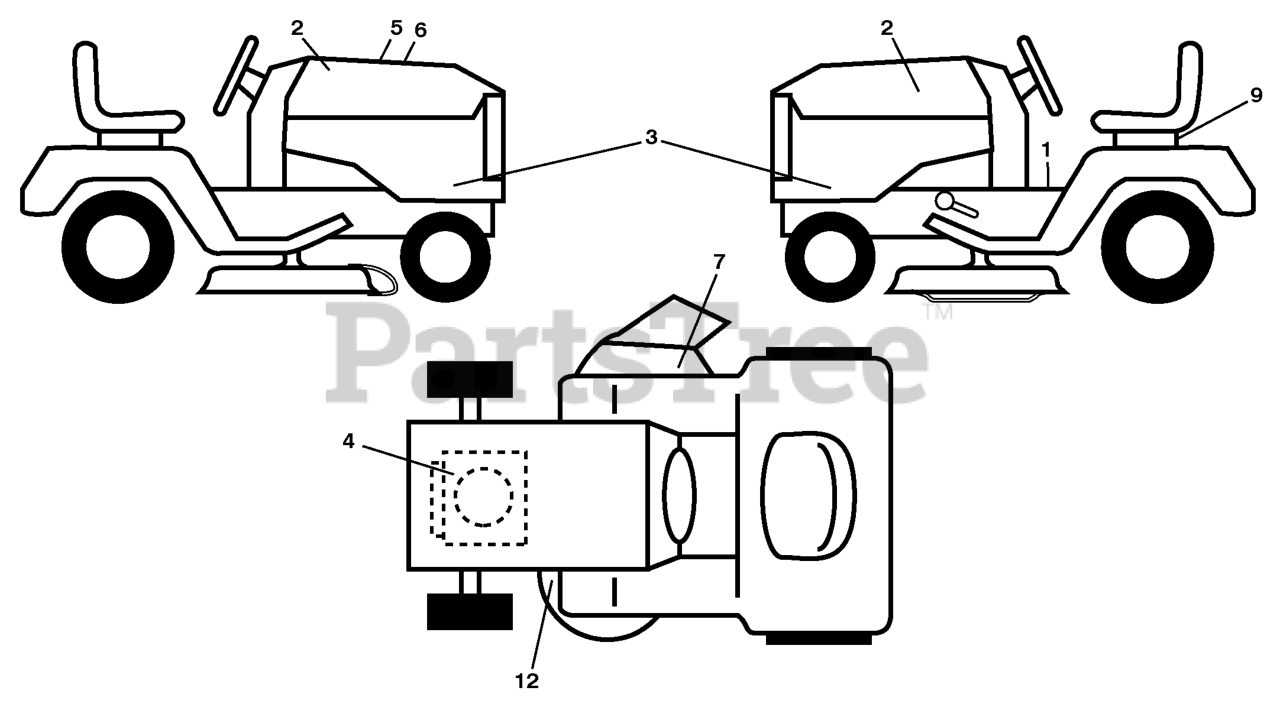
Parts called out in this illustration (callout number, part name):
1	DECAL.FENDER.WARNING.ENG
2	RP.DECAL.BADGE.170MM.TEXTLOGO
3	DECAL.SDPNL.YTH22V46.BS.HUSQ
4	Decal, Engine H.P.
5	DECAL.WARNING.CUST.RESP.E85.
6	Decal, Replacement
7	DECAL.WARN.KEEP.HAND.AWAY
9	DECAL BTRY SYMBOLS
12	DECAL V BELT SCHEMATIC
